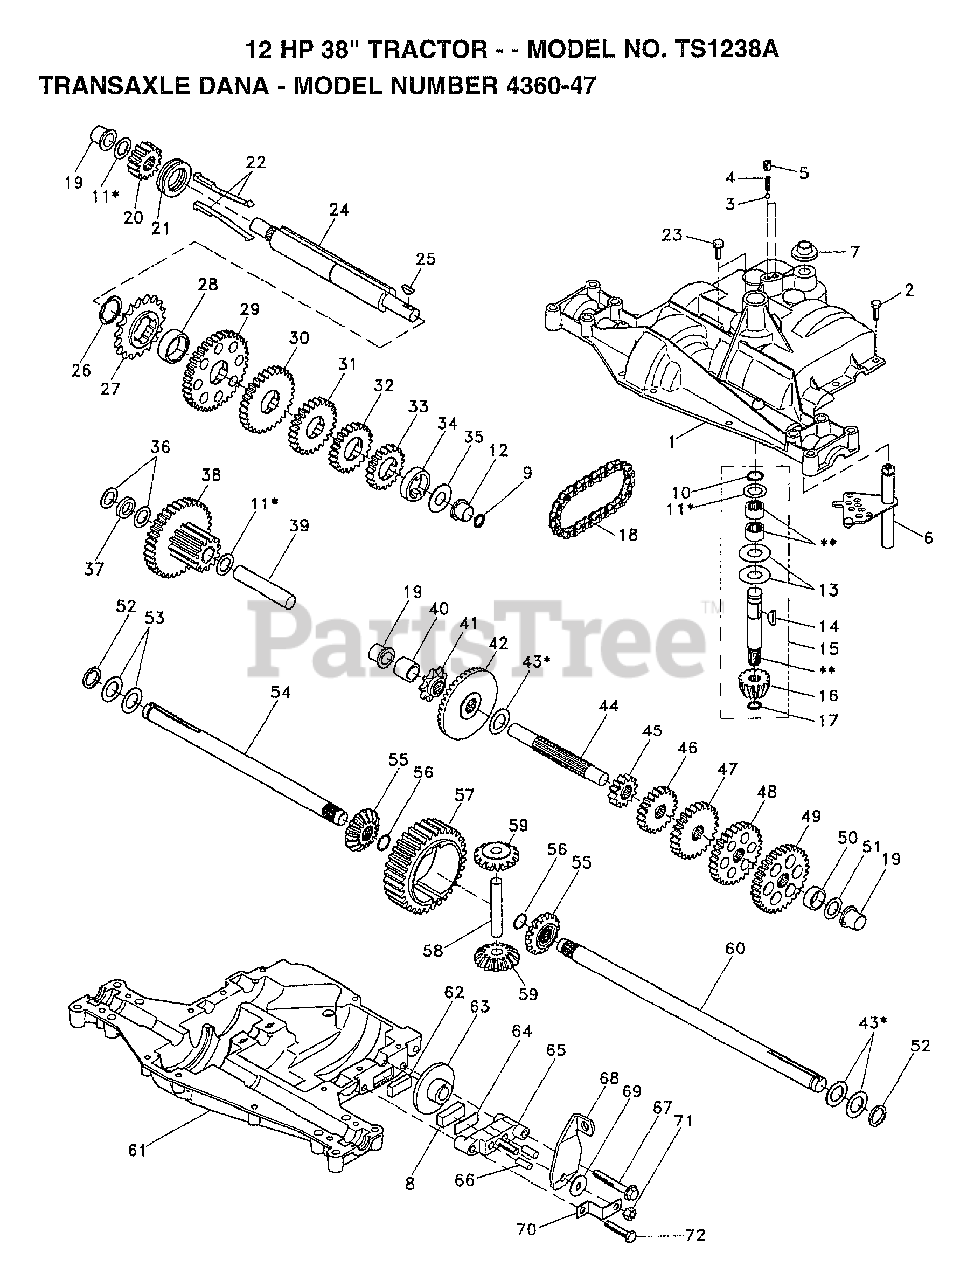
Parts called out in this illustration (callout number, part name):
4	"SPRING, DETENT LT"
5	"SCREW, SET LT"
6	KIT SHIFTER ASM
7	SHIFTER BOOT
8	PUCK T
9	SQUARE RING
10	RETAINING RING LT
11	ASM KIT SHIM 4689
12	"FLANGE, BEARING"
13	WASHER T
14	WOODRUFF KEY
15	AS KIT INPUT SHFT
16	PINION 14T T
17	"RING,RETAINING LT"
18	"CHAIN,24 PTCH LT"
19	BEARING.FLNG.5510
20	GEAR SPUR 14T
21	COLLAR CLUTCH
22	ASM KIT CLTCH KEY
23	SCREW TAP W/SEAL
24	SHAFT INTERM
25	WOODRUFF KEY
26	"RING,RETAINING LT"
27	SPROCKET 18T T
28	SPACER YT
29	KIT.GEAR.12/37TH
31	GEAR 25T LT
32	GEAR SPUR 22 TT
33	SPUR GEAR 19T
34	SPACER
35	"WASHER, PLAIN LT"
36	WASHER 025
37	SPACER
38	ASSM GEAR COMB
39	SHAFT IDLER
40	SPACER T
41	SPROCKET 9T LT
43	ASM KIT SHIM
44	SHAFT T
47	"GEAR, SPUR 25T LT"
48	GEAR 28T T
49	"GEAR, SPUR 31T LT"
51	WASHER 060
52	NEOPRENE WASHER
53	WASHER 031
55	GEAR 15T T
56	"RING,RETAINING LT"
58	SHAFT T
59	GEAR 1ST T
62	PUCK T
63	BRAKE DISC. T
64	SPACER LT
66	PIN T
69	WASHER LT
71	NUT.LOCK.5/16-24
72	"SCREW, TAPPING LT"
